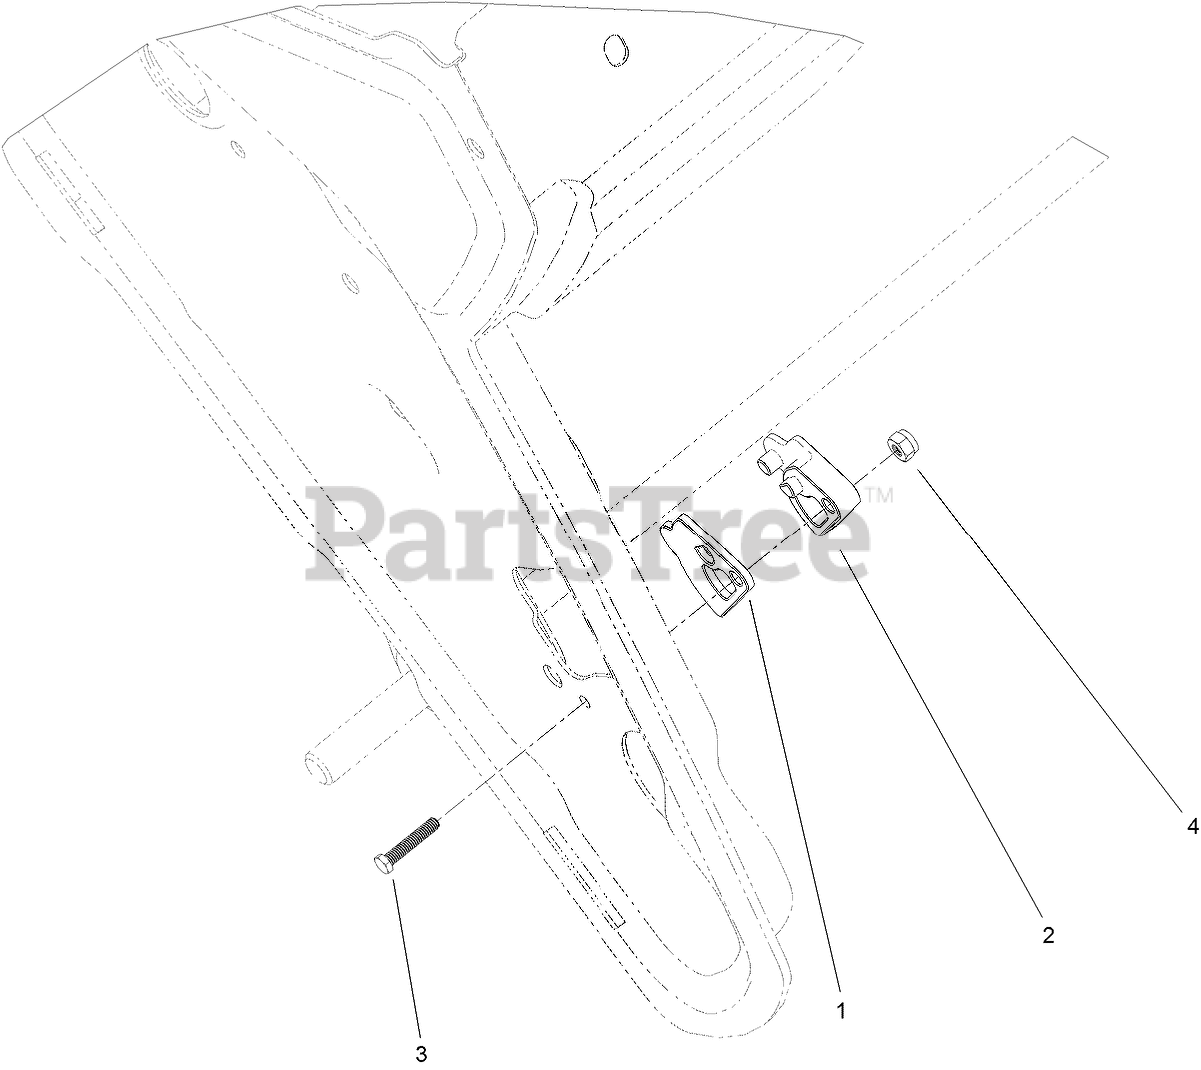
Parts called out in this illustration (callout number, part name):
1	CAP-GUIDE, CABLE
2	GUIDE-CABLE
3	Screw, Machine, Nozzle, 8-32 x 7/8"
4	NUT-HEX, NYLOCK
